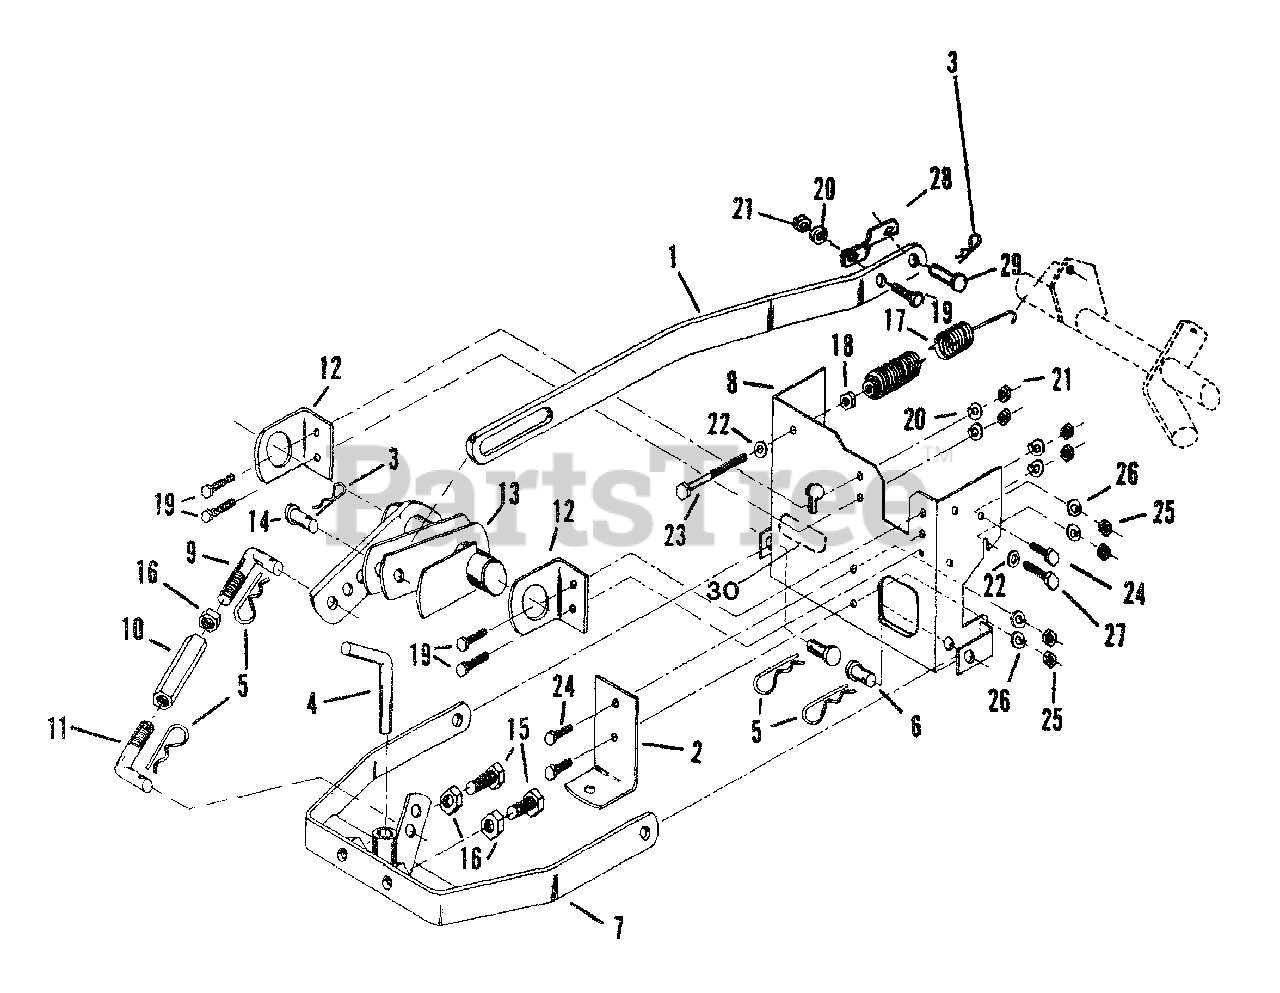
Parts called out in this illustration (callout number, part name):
1	Draw Strap
2	Draw Bar
3	Retaining Spring (Small)
4	Hitch Pin
5	Retaining Spring (Large)
6	Clevis Pin 5/8" x 1-1/2"
7	Bail Assembly
8	Hitch Bracket
9	Lift Link (R.H.) Long
10	Turnbuckle
11	Lift Link (L.H.) Short
12	Pivot Bracket
13	Lift Arm Assembly
14	Clevis Pin 1/2" x 1-1/4"
15	Hex Bolt 5/8"-11 x 3" (Full TH'D)
16	Hex Nut 5/8"-11
17	Lift Assist Spring
18	Hex Jam Nut 3/8"-16
19	Hex Bolt 5/16"-18 x 1"
20	Lock Washer 5/16"
21	Hex Nut 5/16"-18
22	Washer 3/8"
23	Spring Assist Adjust Bolt 3/8" x 5-1/2"
24	Hex Bolt 3/8" x 1"
25	Hex Nut 3/8"-16
26	Lock Washer 3/8"
27	Hex Bolt 3/8" x 1-1/4"
28	Draw Strap Clevis
29	Clevis Pin 3/8" x 1-1/8"
30	Instructions Label
